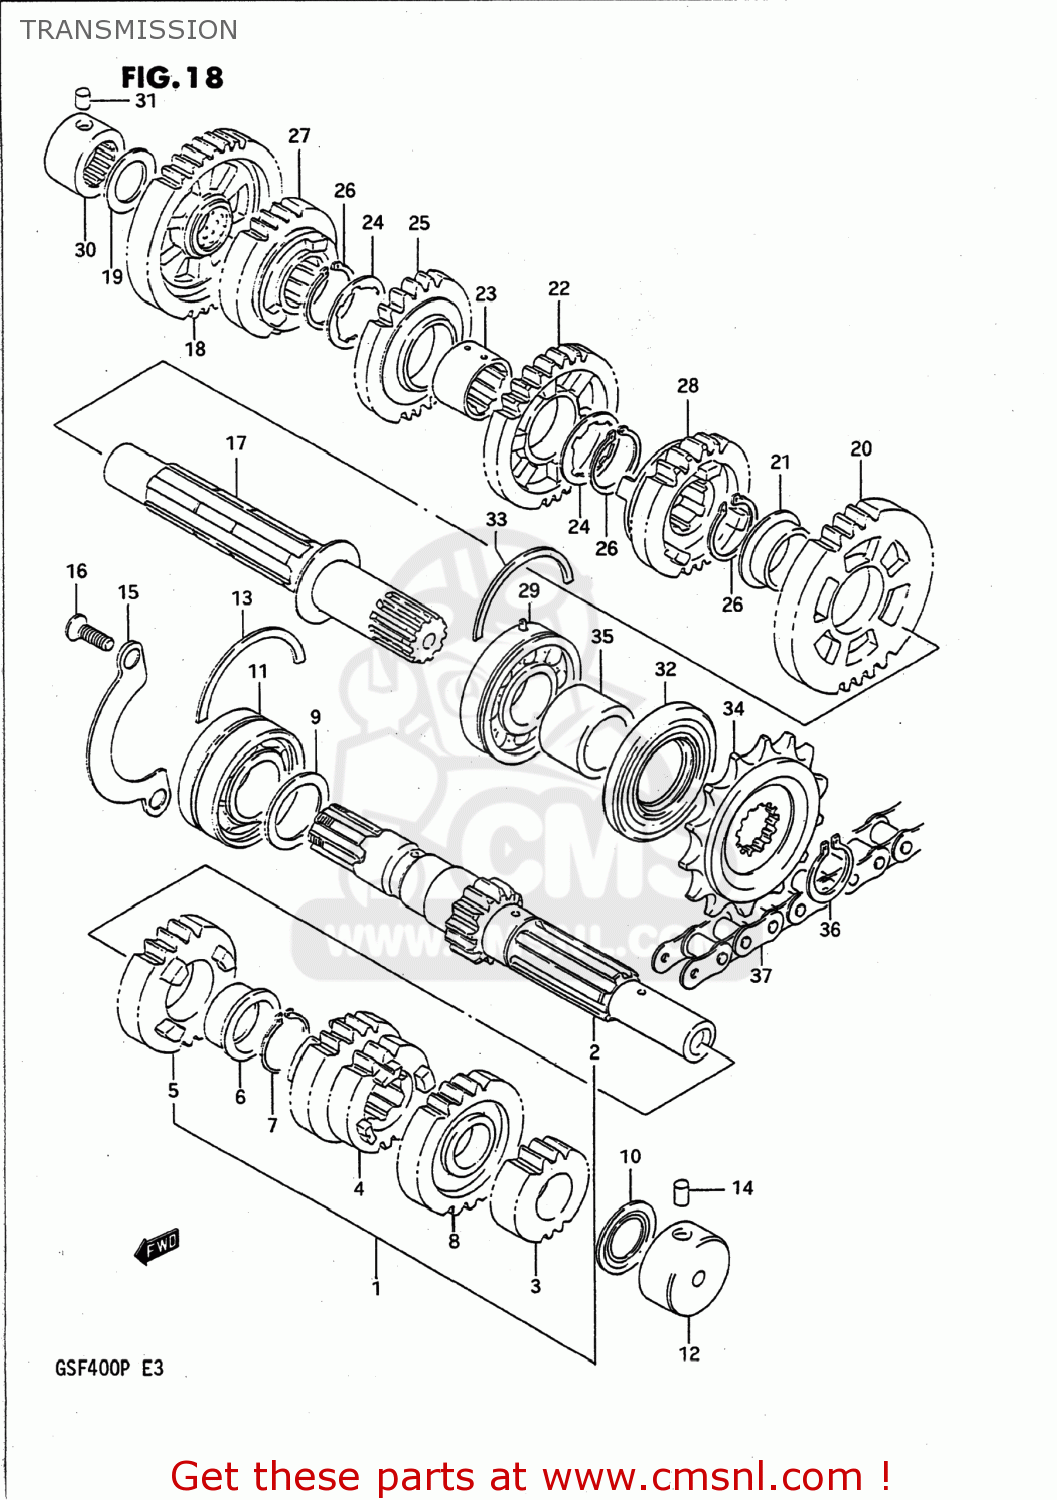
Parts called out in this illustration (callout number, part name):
1	SHAFT,COUNTER
2	COUNTER SHAFT NT:11
3	GEAR,2ND DRIVE
4	GEAR,3RD & 4TH DRIVE(NT:16/16)
5	GEAR,5TH DRIVE(NT:24)
6	BUSH
7	CIRCLIP
8	GEAR,SIXTH DRIVE
9	WASHER
10	SEAL,OIL(17X28.5X2.5)
11	BEARING(25X52X19.6)
12	BEARING(17X34X16)
13	C RING
14	PIN
15	RETAINER,CNTR SHAFT BEARING
16	SCREW
17	SHAFT,DRIVE
18	GEAR,FIRST DRIVEN
19	WASHER,THRUST
20	GEAR,2ND DRIVEN
21	BUSH
22	GEAR,3RD DRIVEN
23	SPACER,3RD DRIVEN GEAR
24	WASHER,LOCK
25	GEAR,FOURTH DRIVEN
26	RING,SNAP
27	GEAR,5TH DRIVEN(NT:30)
28	GEAR,SIXTH DRIVEN
29	BEARING
30	BEARING(20X34X20)
31	PIN
32	SEAL,OIL(30X56X6)
33	C RING
34	SPROCKET,ENGINE(NT:14)
35	SPACER(22X30X21.4)
36	CIRCLIP
37	CHAIN,DRIVE(525V9X114LE)
